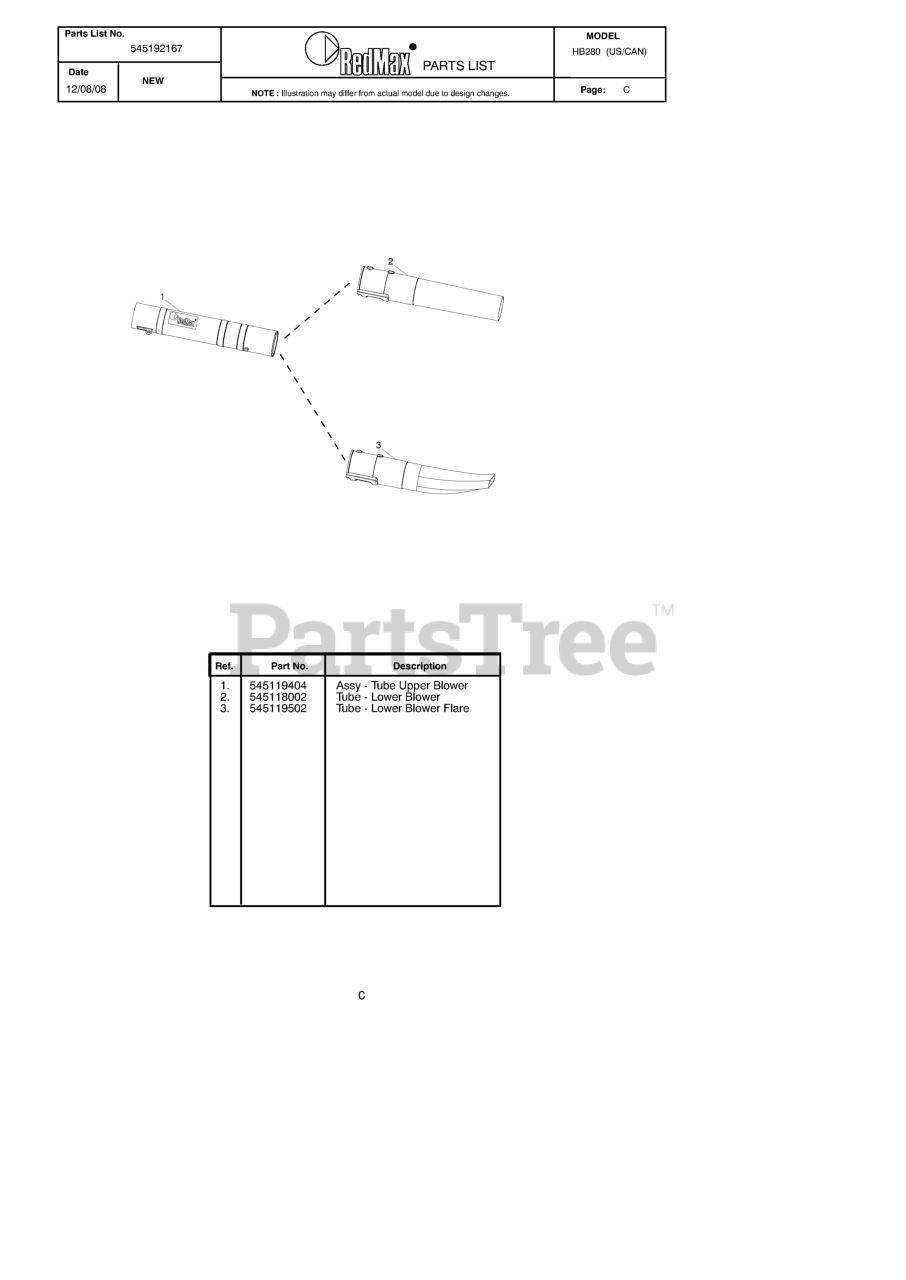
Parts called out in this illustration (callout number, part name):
1	ASSY - TUBE UPPER BLOWER
2	TUBE - LOWER BLOWER
3	TUBE-LOWER BLOWER FLARE
